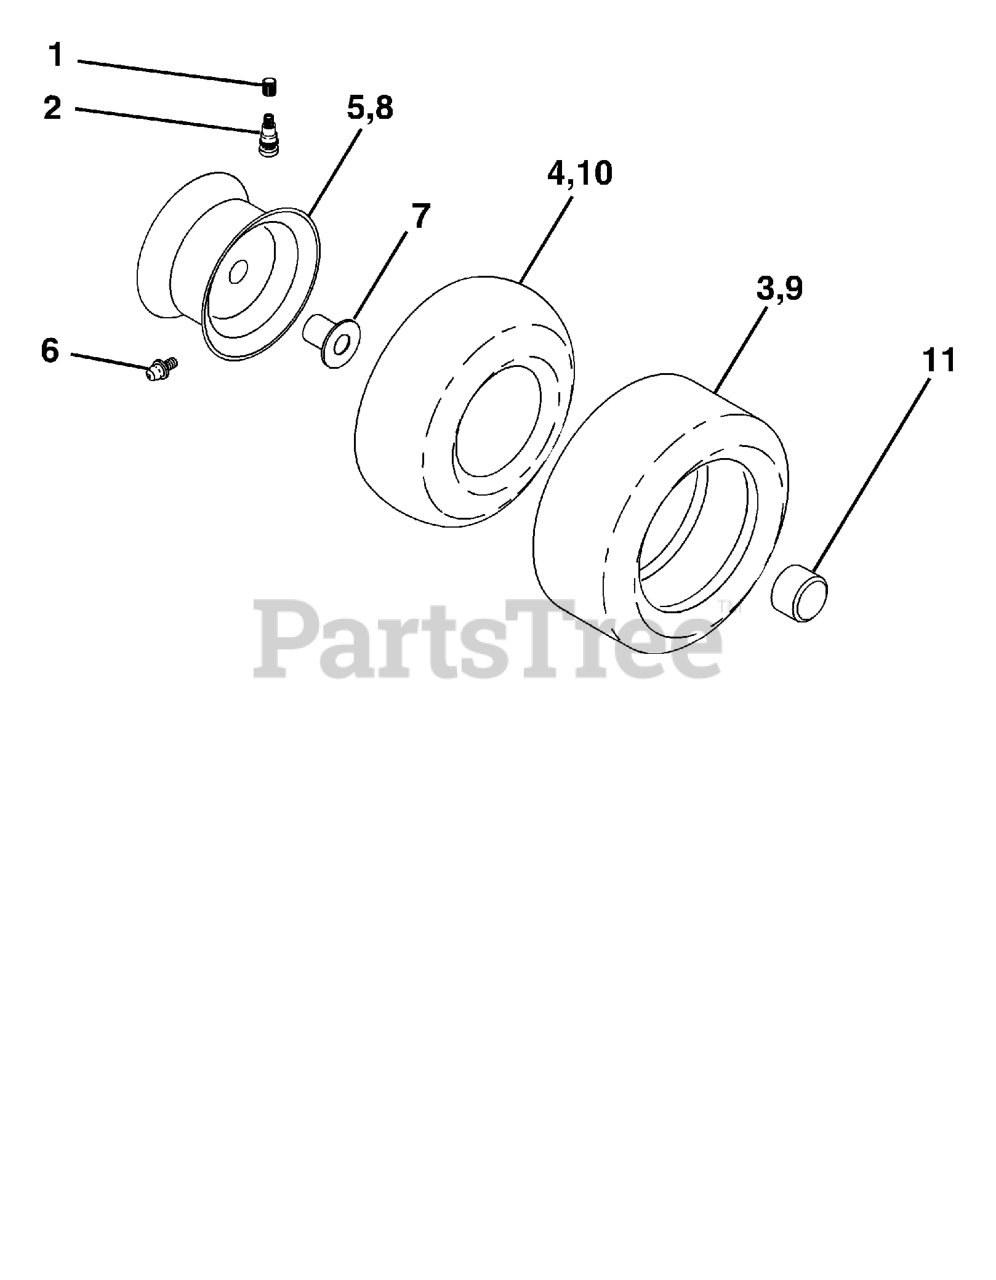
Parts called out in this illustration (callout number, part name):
1	VALVE CAP
2	VALVE STEM LT
3	TIRE HEAVY DUTY
4	TUBE.5.3/4.5/6
5	RIM ASM 6" FRONT SILVER
6	FITTING LT
7	BEARING T
8	RIM ASM 8" REAR SILVER
9	TIRE.20X8-8.TURF.SAVER
10	TUBE
11	CAP, AXLE BLK
